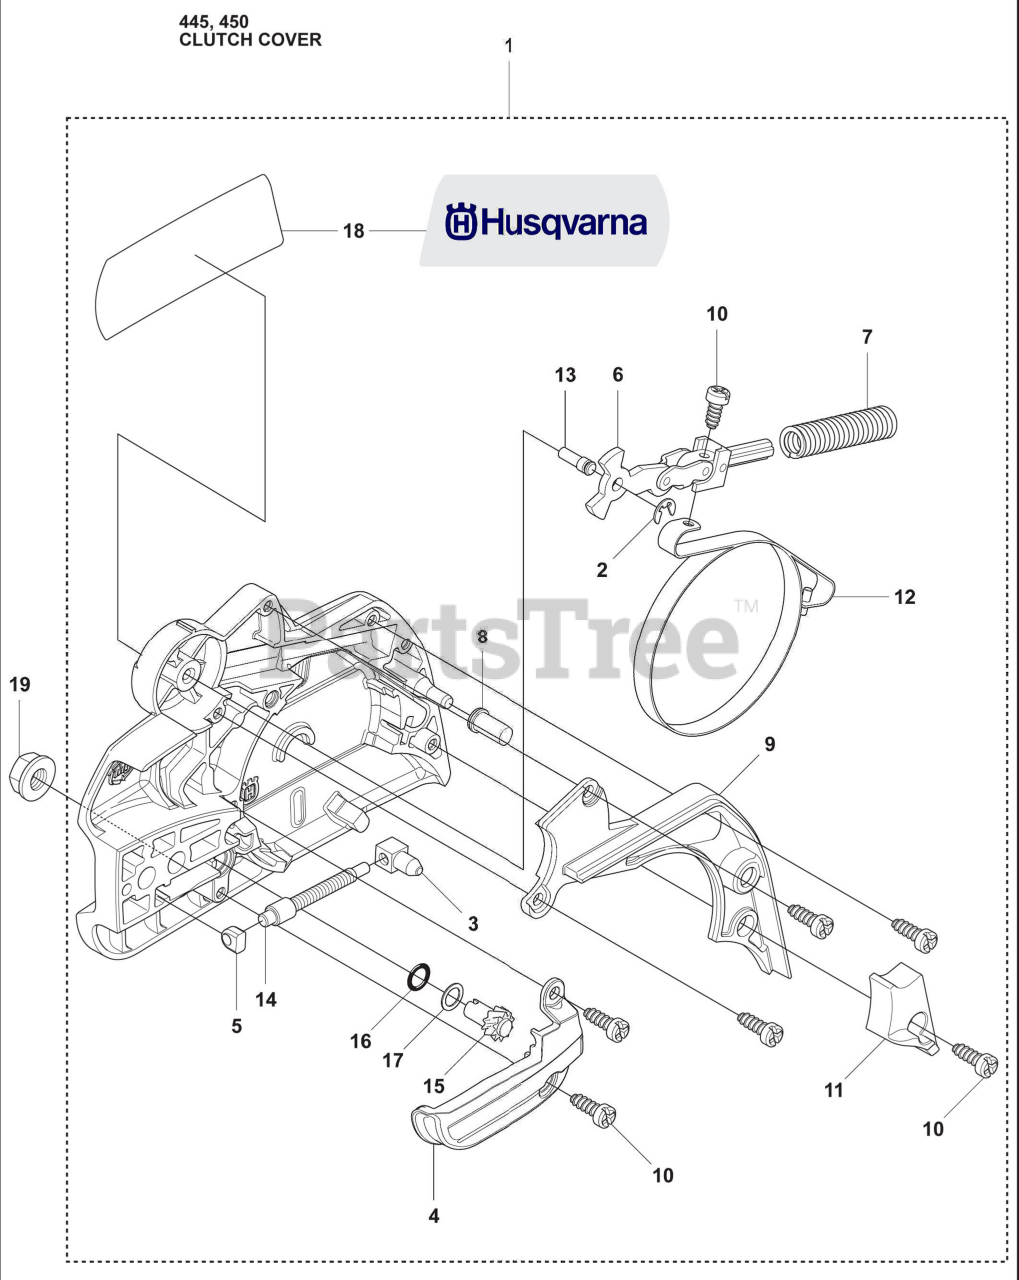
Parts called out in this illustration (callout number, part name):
1	Clutch Cover Assembly
2	Bar Retainer
4	Chain Guide
9	Chain Brake Cover
11	Chain Wear Guard
12	Brake Band
14	Worm Screw
15	Worm Wheel
18	Label, 400 Series
19	Flange Hex Nut, M8
